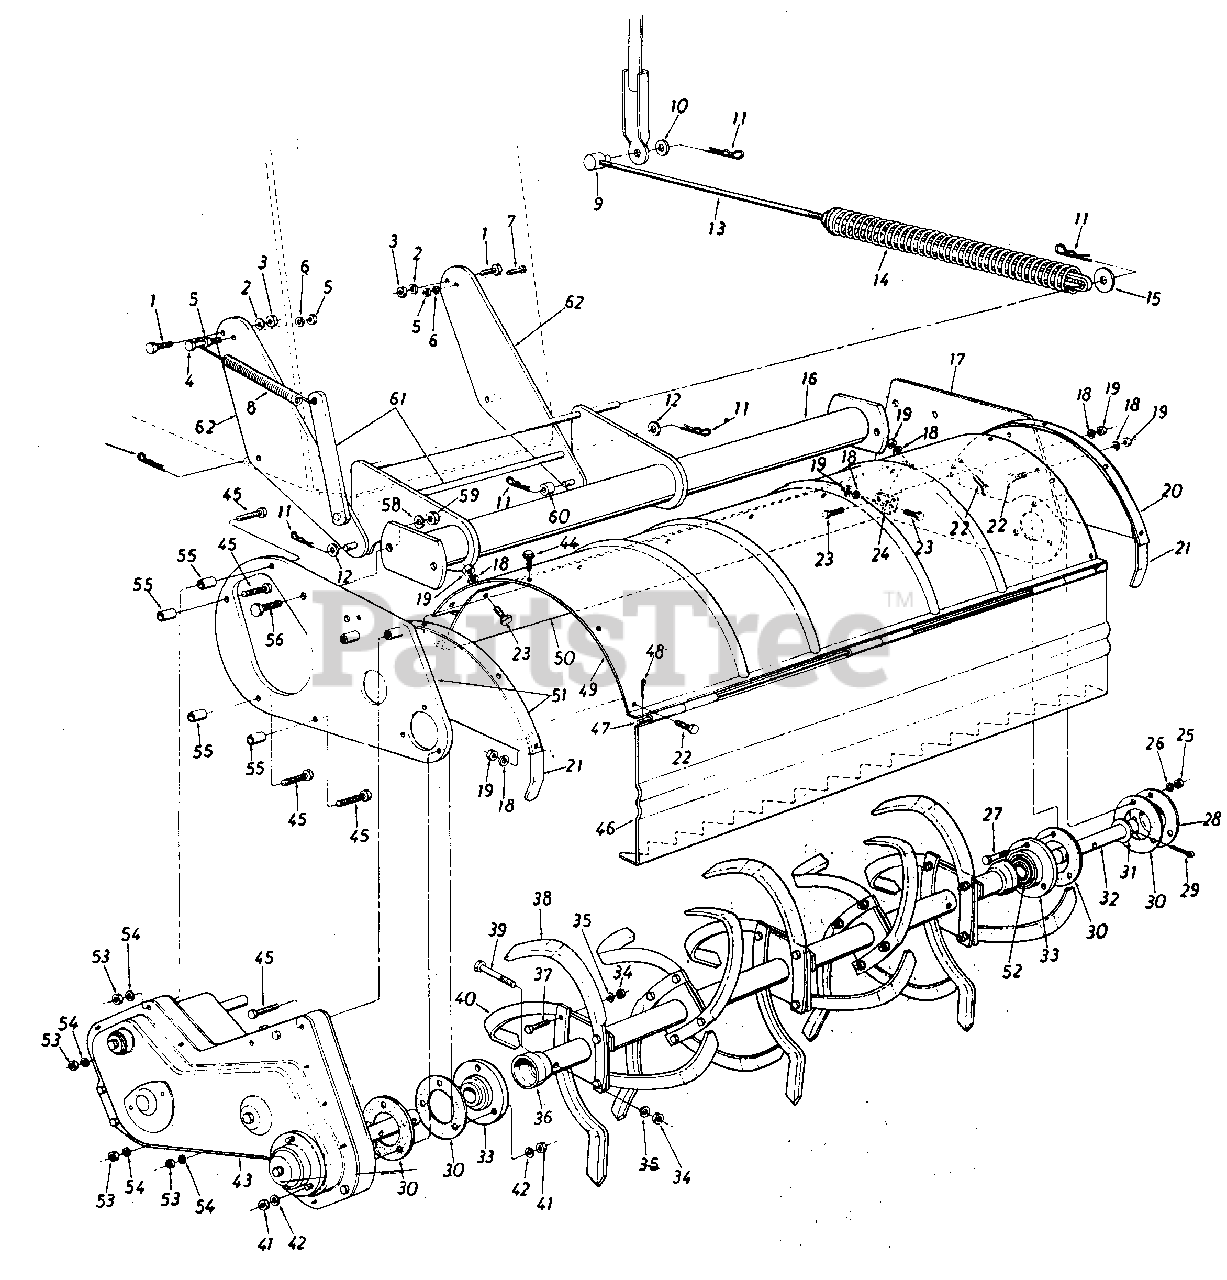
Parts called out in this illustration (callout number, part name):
1	Hex Bolt 3/8-24 x .88" Lg.*
2	L.-Wash. 3/8" I.D. Heavy Duty
3	Hex Nut3/8-24Thd.*
4	Hex Bolt 5/16-24 x 1.50" Lg.*
5	Hex Nut 5/16-24Thd.*
6	L.-Wash. 5/16" I.D.*
7	Hex Bolt 5/16-24 x 1.00" Lg.*
8	Extension Spring .56" O.D. x 7.75" Lg.
9	Adjustment Ferrule 1/2-13 Thd.
10	Fl.-Wash. .640" I.D. x 1.24" O.D. x.060
11	Intern. Cotter Pin 1/2" Dia.
12	Fl.-Wash. .510" I.D. x 1.0" O.D. x .060
13	Lift Rod Ass'y. 39.0" Lg.
14	Compression Spring 1.50" O.D. x 15.0" Lg.
15	Fl.-Wash. .51" I.D. x 1.50" O.D. x .075
16	Pivot Bracket Assembly
19	Hex Nut 5/16-24 Thd.*
23	Hex Bolt 5/16-24 x .62" Lg. *
24	Chute Pivot Bracket
25	Hex Cent. L-Nut 5/16-18 Thd.
26	L.-Wash. 5/16" I.D.*
27	Hex Bolt 5/16-18 x 1.0" Lg. (Grade 5)
30	Gasket for Brg. Housing
31	Fl.-Wash. 1.25" I.D. x 2.00" O.D x .06
32	Tine Shaft R.D. 1.25" Dia. x 6.25" Lg.
33	Bearing Housing w/ Bearing
34	Hex Nut 3/8-24 Thd.*
35	L.-Wash. 3/8" I.D. Heavy Duty
38	Tine 14" x 5/16"
39	Hex Bolt 3/8-24 x 2. 25" Lg.*
40	Tine 14" x 5/16"
41	Hex Cent. L.-Nut 5/16-18 Thd.
42	L.-Wash. 5/16" I.D.*
43	Chain Case Ass'y. Comp.
44	Hex Wash. TT Tap. Scr. 5/16-1 8 x .62" Lg.
45	Hex Bolt 1/4-20 x 2.75" Lg.*
48	Cotter Pin 1/8" Dia. x 1.00" Lg. *
53	Hex Nut 1/4-20Thd.*
54	L.-Wash. 1/4" I.D.*
55	Spacer.28" I.D. x .62" O.D. x .90" Lg.
56	Hex Bolt 1/2-13 x 1.00" Lg.*
58	L.-Wash. 1/2" I.D.*
59	Hex Nut 1/2-13 Thd.*
60	Spacer .50" I.D. x 1.00" O.D. x.50" Lg.
61	Idler Bracket Support Arm Ass'y.
62	Pivot Bracket Support
